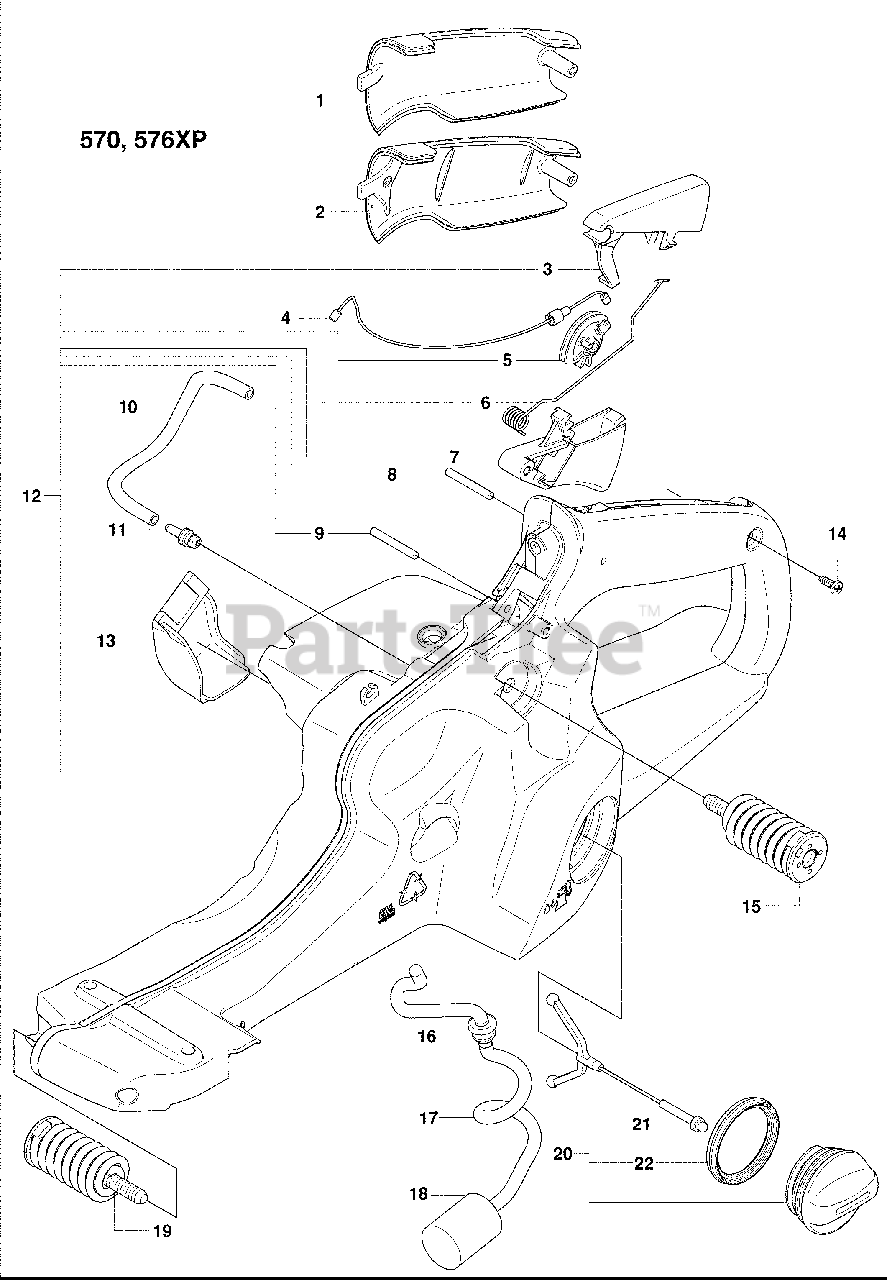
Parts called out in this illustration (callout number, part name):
1	Cover
2	Cover
3	Throttle Lock
4	Throttle Wire
5	Cable Lever
7	Throttle Trigger
8	Pin
9	Pin
10	Fuel Hose, Straight 105
11	Tank Vent Assembly
15	Vibration Absorber
16	Fuel Line Grommet
17	Fuel Hose, Spiral 300
18	Fuel Filter Kit
19	Vibration Absorber
20	Fuel and Oil Tank Cap
22	Sealing Gasket
